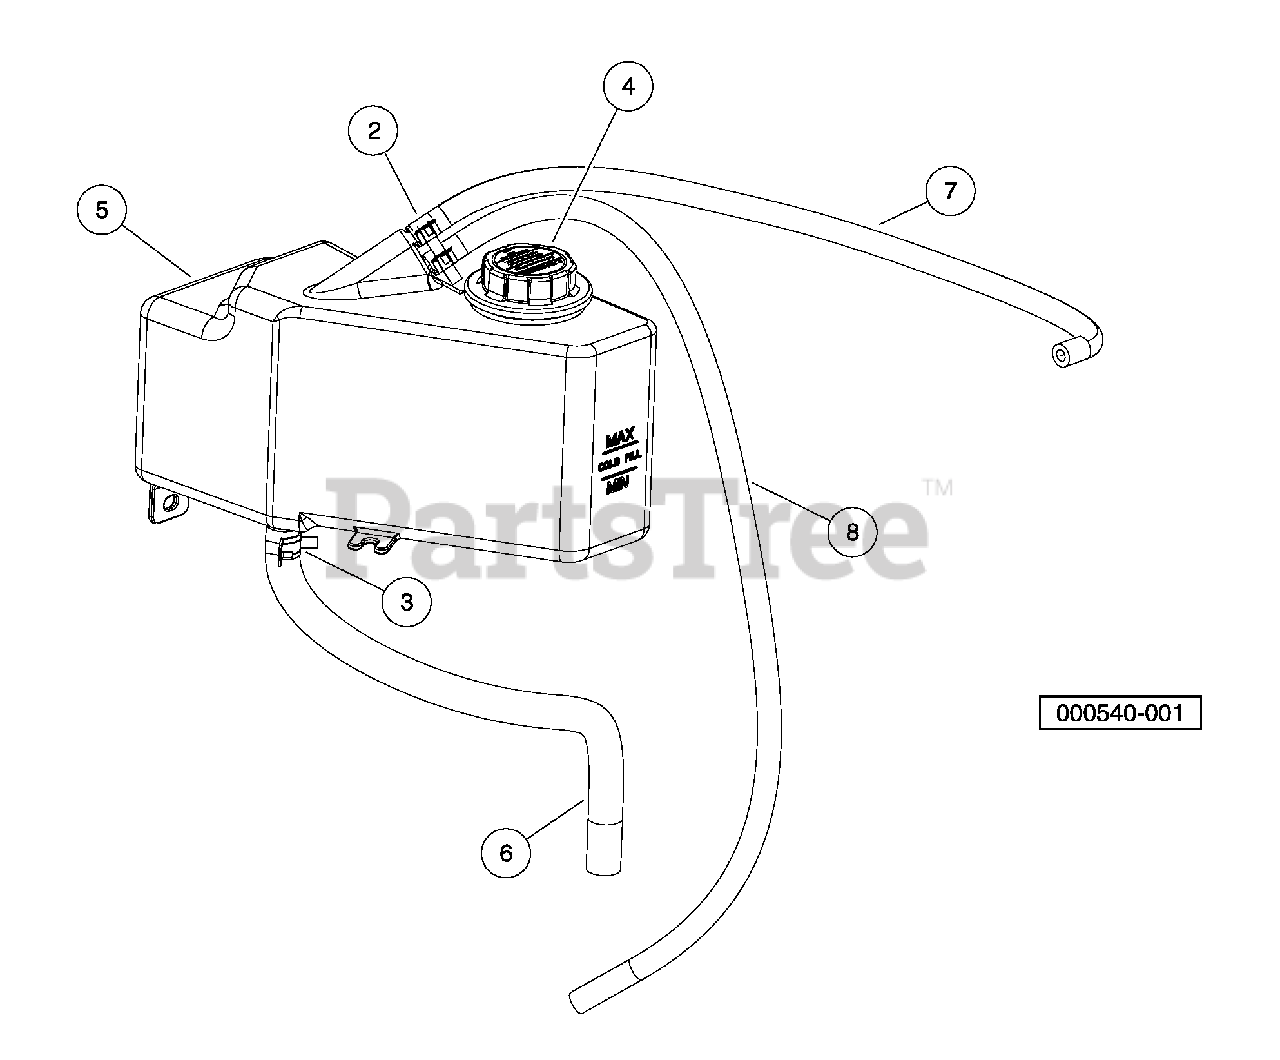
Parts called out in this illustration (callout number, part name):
1	Asm, Coolant Bottle
2	Clamp, Hose, CTB 15mm
3	Clamp, Hose, CTB 22mm
4	Cap, Radiator
5	Bottle, Coolant
6	Hose, Cut, 5/8, 445
7	Hose, Cut, Coolant, 700
8	Hose, Cut, Coolant, 1100
